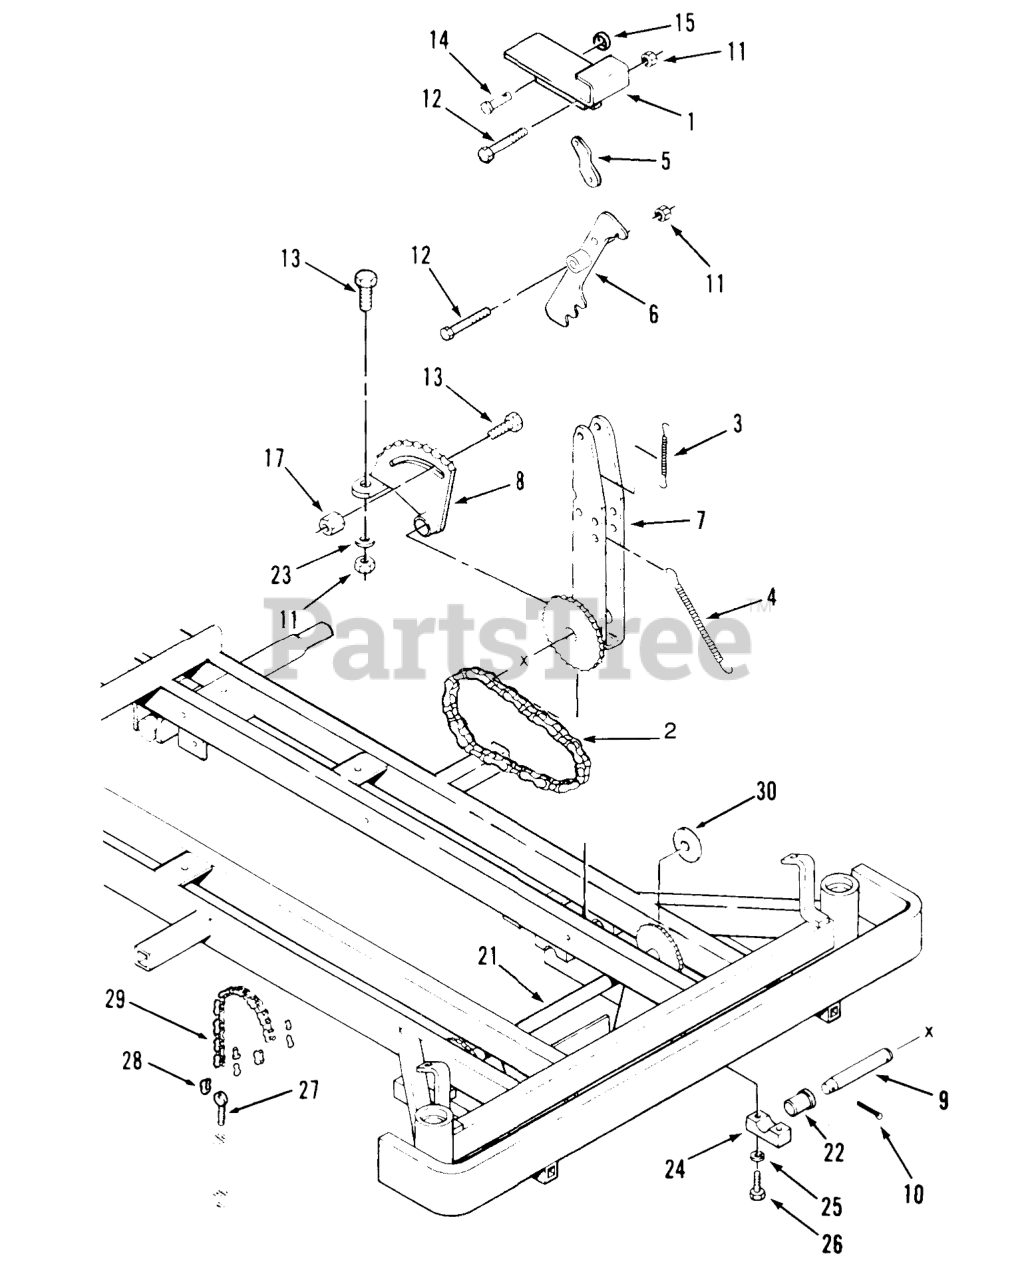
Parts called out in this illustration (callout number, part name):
1	PEDAL-FOOT 10218- B
2	CHAIN-FOOT PEDAL DR
3	SPG-NEUTRAL 20217-35
4	SPRING - EXTENSION
5	PIVOT-LINK B
6	LIFT-ARM PWL B
7	ASSY-LVR ARM 1022 B
8	HEIGHT CONTROL SP B
9	PIN-PEDAL
10	PIN-COTTER
11	NUT-LOCK, NI
12	SCREW-HH
13	SCREW-HH
14	PIN-LOCK
15	E RING
17	HEX-STOP NUT N-140
21	ASM-Sprocket
22	BEARING-FLANGED
23	WASHER-LOCK/SP
24	ASS'Y-CR SH PIVOT BK B
25	WASHER-FLAT
26	SCREW-HH
27	EYE-BOLT 3/8-16X2.50
28	MASTER LINK CHAIN
29	CHAIN-DECK LIFT
30	Washer
